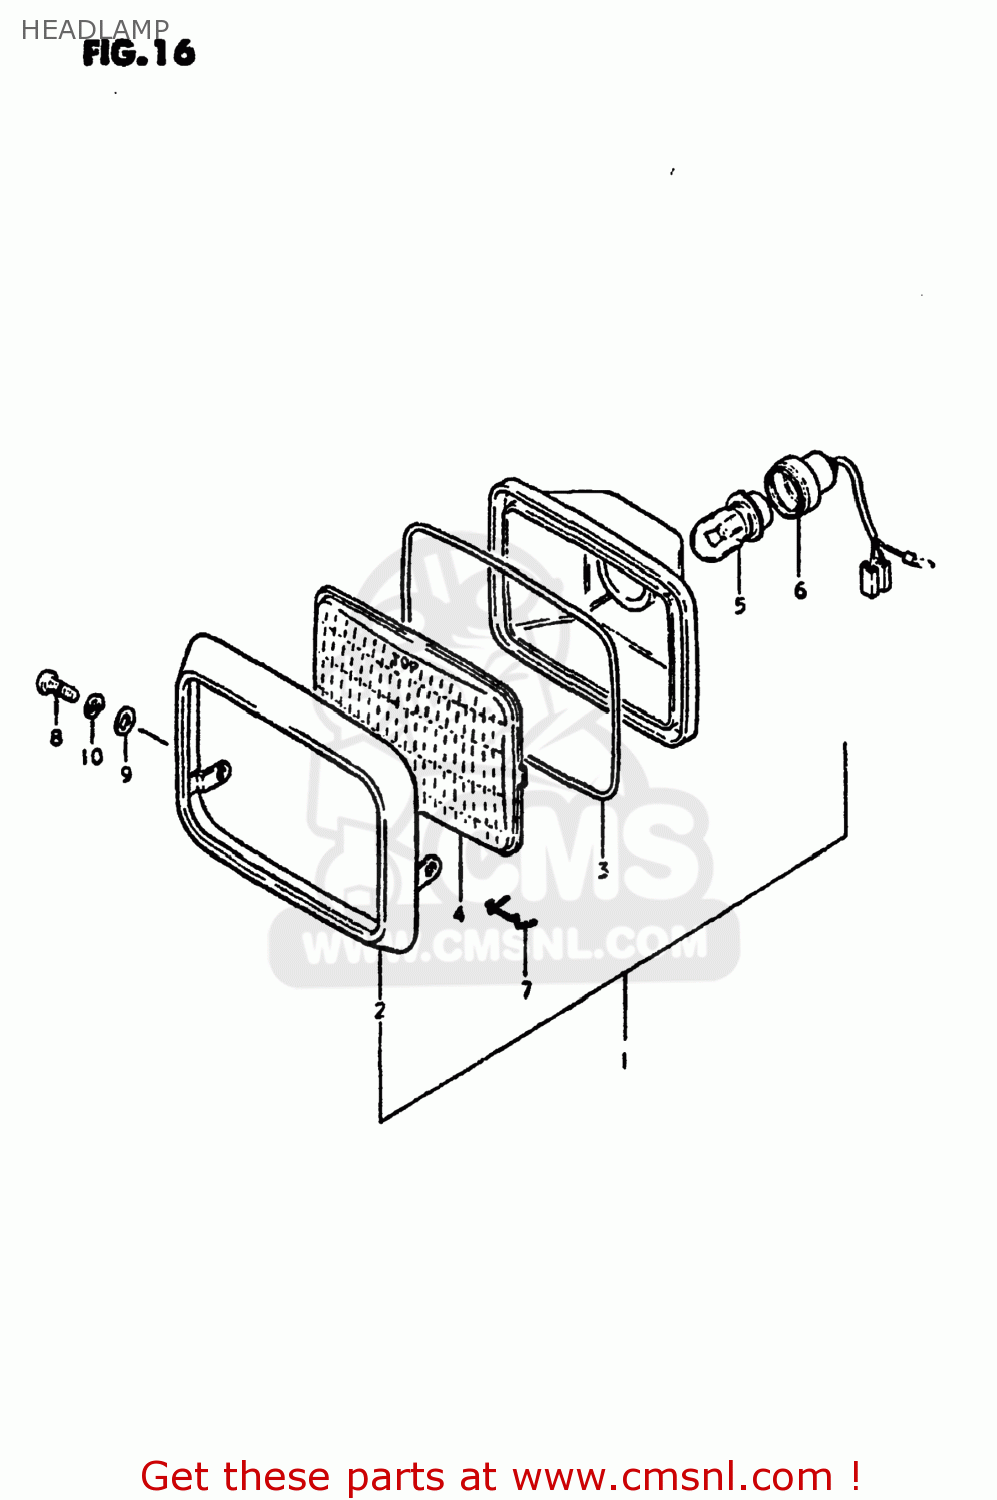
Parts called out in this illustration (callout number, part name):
1	LAMP ASSEMBLY,HEAD
2	RIM,HEADLAMP
3	GASKET,HEADLAMP LENS (NAS)
4	LENS,HEADLAMP (PLASTIC)
5	BULB(6V15/15W/STANLEY,A3598HA)
6	SOCKET,BULB
7	SPRING,HEADLAMP UNIT
8	SCREW
9	WASHER
10	LOCK WASHER
